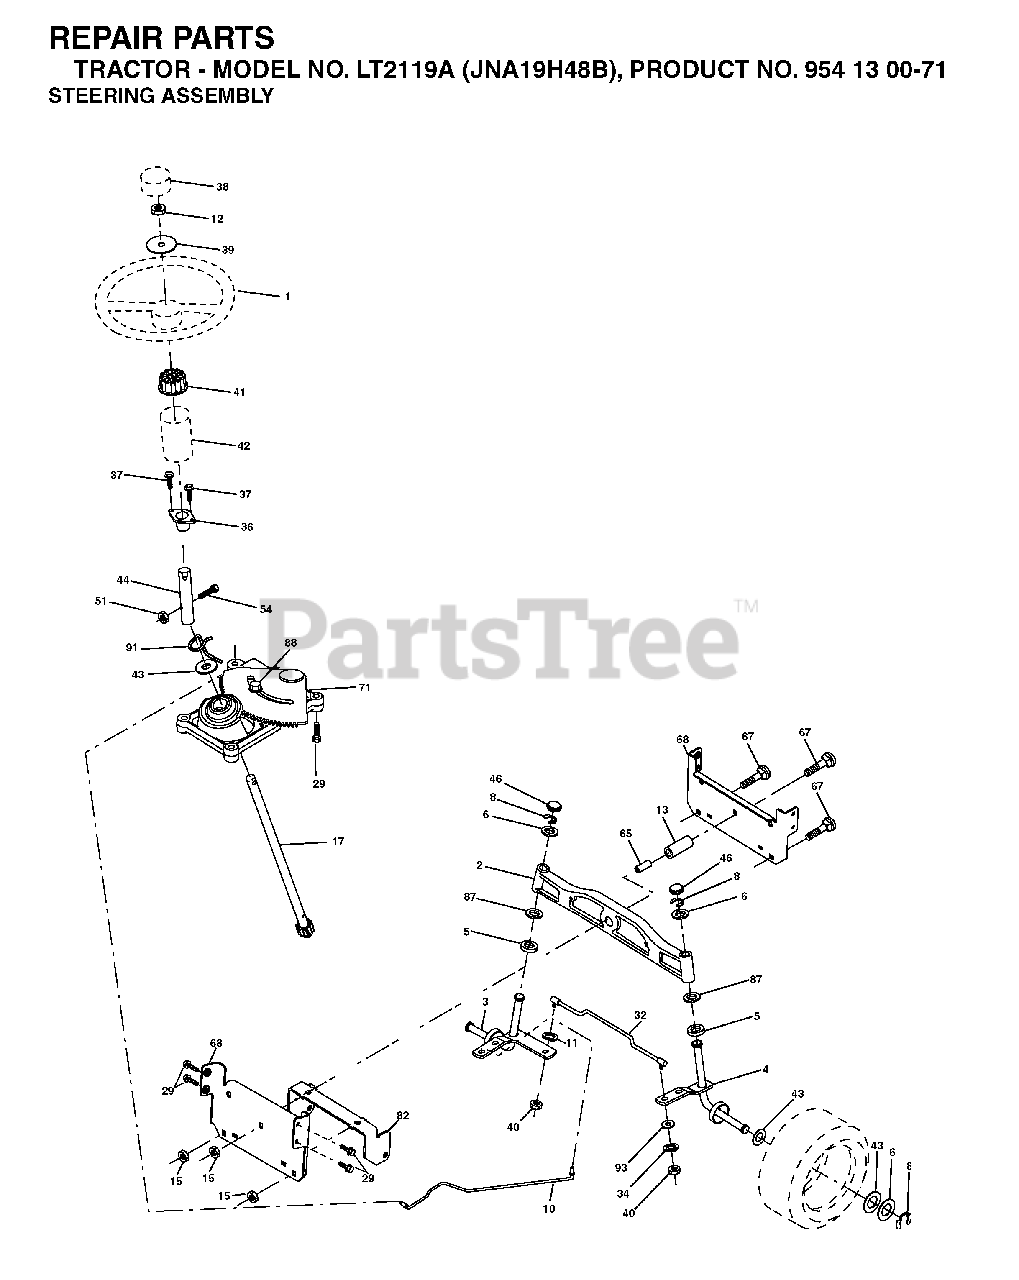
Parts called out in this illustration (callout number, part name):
2	AXLE ASSY FRONT
3	SPINDLE.ASM.LH.15"TIRES
4	SPINDLE.ASM.RH.15"TIRES
8	RING CLIP
10	DRAGLINK.15".TIRES.2001
11	WASHER, LOCK 3/8
12	NUT.HEX.1/2-20
13	TUBE, PIVOT AXLE
15	NUT
17	SHAFT ASM, STEERING
29	SCREW 3/8-16X3/4
32	ROD TIE BALL J
34	WASHER, LOCK 3/8
36	BUSHING, STEERING
40	GRIPCO NUT
41	STEERING WHEEL ADAPTOR
42	BOOT.STEERING.SHAFT.BLACK
44	EXT, STEERING SHAFT
46	CAP.SPINDLE
51	CROWN LOCKNUT
65	SPACER BRACE AXLE
67	BOLT
68	BRACE.AXLE.15"TIRES
71	STEERING ASM
82	BRACKET
87	WASHER, FLAT .781 X 1 1/2"
88	BOLT, SHOULDER 7/16-20
91	CLIP.STEERING
93	WASHER
